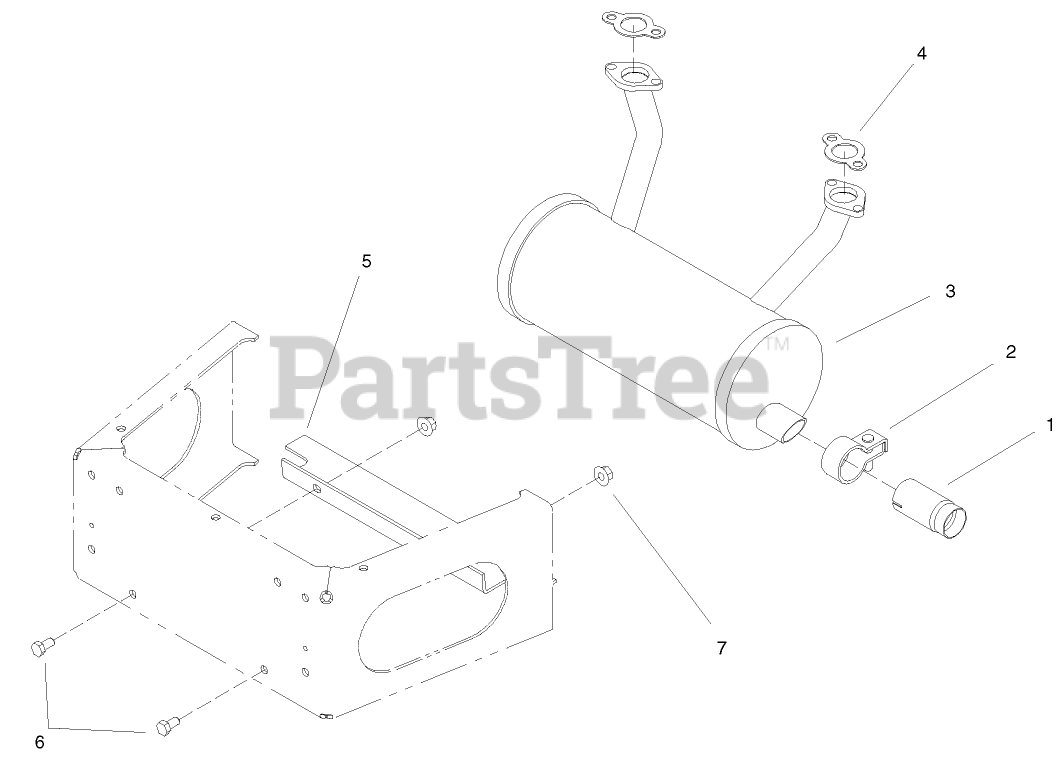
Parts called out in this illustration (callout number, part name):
1	ARRESTER-SPARK
2	CLAMP-MUFFLER
3	Muffler (only on:74170, 74176, 74270)
3	Muffler (only on:74172, 74174, 74178, 74197, 74171)
3	Muffler (only on:74173, 74175, 74179, 74198)
4	Gasket (only on:74170, 74176, 74270)
4	Gasket (only on:74172, 74174, 74178, 74197, 74171)
4	Gasket (only on:74173, 74175, 74179, 74198)
5	DEFLECTOR-LOWER FRAME
6	SCREW-HH
7	NUT-HF
